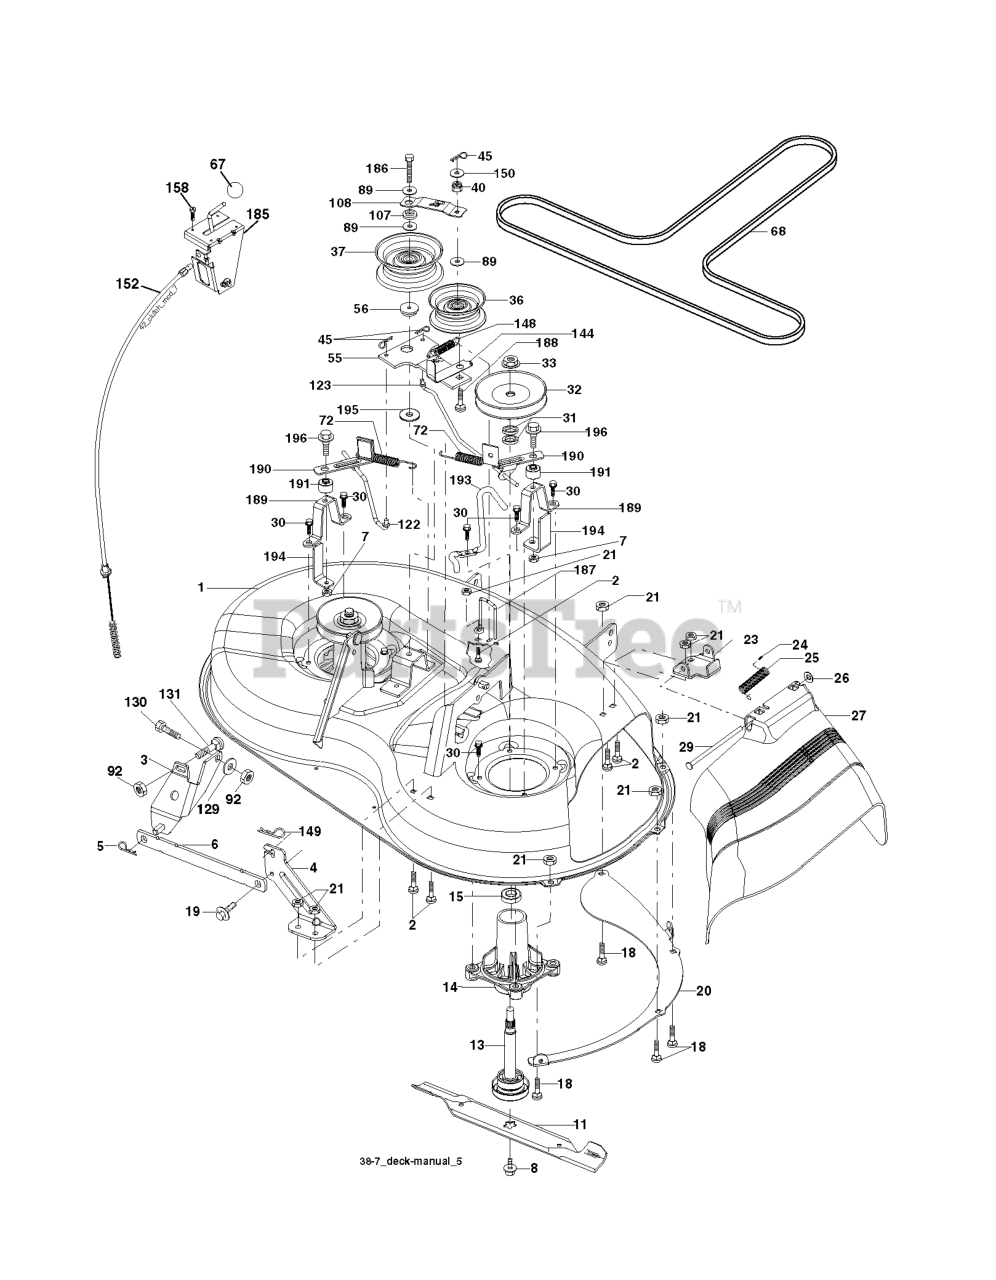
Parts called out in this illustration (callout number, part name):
1	DECK SVCX1 38/94 192556X431
2	RP BOLT 5/16-18 X3/4 ZN/YEL GR
3	BRKT ASM SWAY BAR
4	BRACKET DECK SWAY BAR 38"/42"
5	RETAINER-SPRNG RB
6	BAR SWAY DECK
7	NUT.71038.31-18.HEX.NYLOCK
8	BOLT.WASHER.ASM.7/16-2
11	BLADE 38" PREMIUM
13	SHAFT.ASM.MDRL.N/GREASE.38
14	RP.HOUSING.MANDREL.4PT.
18	BOLT
19	BOLT SHD 5/16-18
20	BAFFLE.VORTEX.FRONT.38"
21	LOCKNUT
23	BRKT.DEFLECTOR.38"2005+
24	CAP-SLEEVE LT
25	SPRING.TORSION.DEFLECT
26	NUT PUSH M
27	SHIELD.DEFLECTOR.MWR.38-7/97CM
29	ROD.HINGE
30	SCREW, WASHER HEAD
31	WASHER.SPACER.MANDREL
32	PULLEY MANDREL
33	NUT.FLANGE.LOCK.TOP
36	FLAT IDLER PULLEY
37	PULLEY.IDLER.FLAT.UNPLATED
45	RETAINER M
56	SPACER.RETAINER.MOWER
67	KNOB T (3/8 HOLE)
68	V-BELT.MOWER.38"2005+
72	SPRING.BRAKE.RETURN.38"
89	WASHER
92	NUT
107	SPACER.IDLER.ARM
108	STIFFENER.IDLER.ARM
122	LINK.BRAKE.38"LEFT.2007
123	LINK.BRAKE.38"RIGHT
129	WASHER
131	BOLT D
144	KEEPER BELT
148	IDLER RETURN SPRING
149	SPRING.RETAINER.YELLOW.ZINC
152	CABLE.CLUTCH.38".SERVICE
158	SCREW
185	HEAD ASM. CABLE CLUTCH
186	SCREW.HXWSH.3/8
187	KEEPER BELT
188	BOLT, CARRIAGE IDLER
189	STAND, BRAKE
190	ARM, BRAKE
191	BRAKE.SPACER.38".DECK
192	BOLT/WASHER ASM 5/16-18
193	KEEPER BELT RH MANDREL
194	GUARD BRAKE
195	WASHER 12/32X2X10GA
